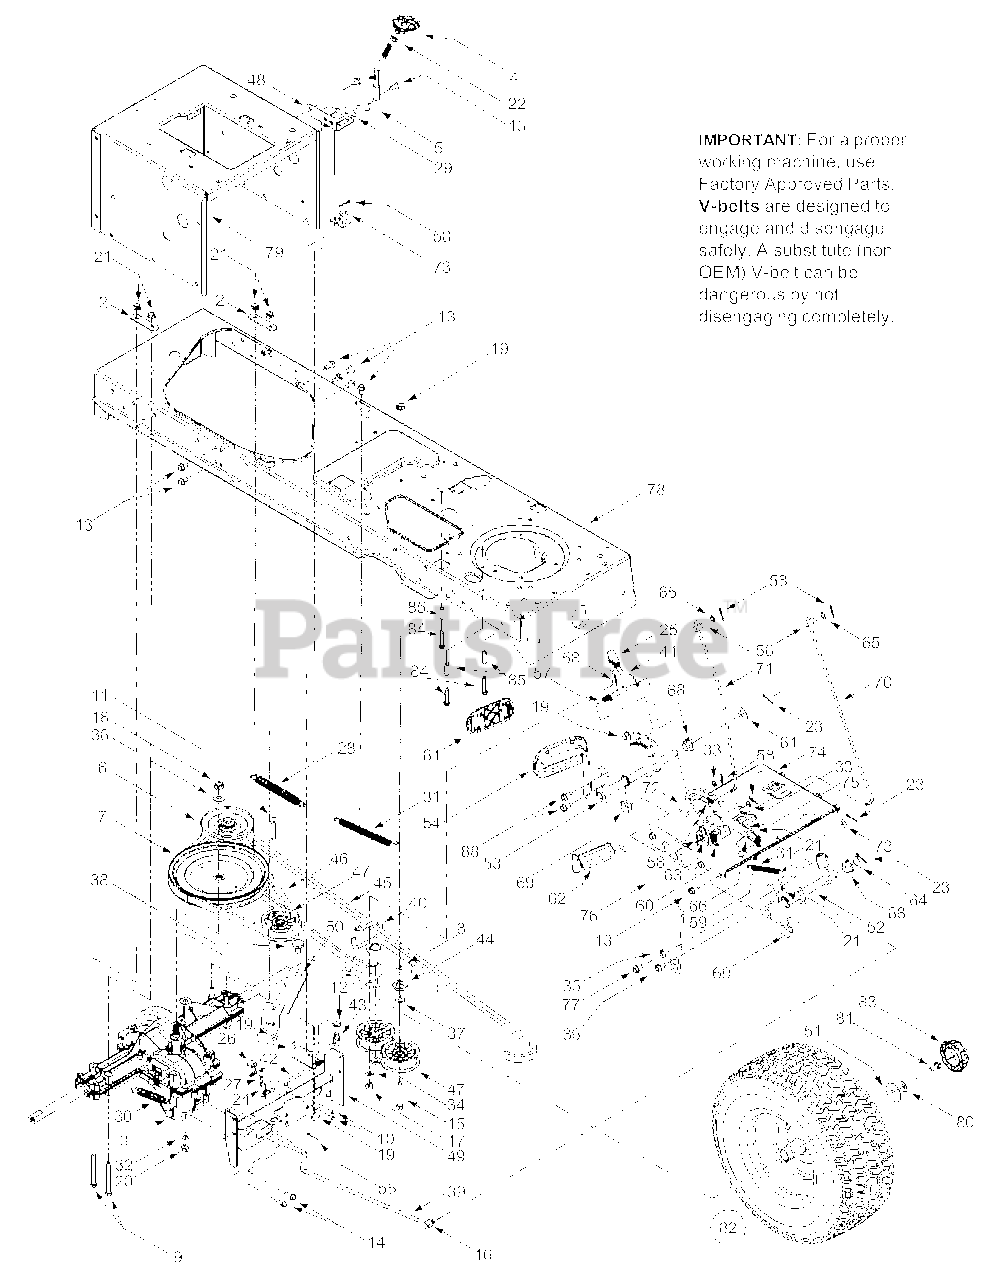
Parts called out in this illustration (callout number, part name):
3	Single-speed Transmission Assembly
4	Shifter Knob
5	Shift Lever
6	Variable-speed Pulley Assembly
7	Transmission Pulley, 8.5 x .5-36
8	Double-idler Bracket
9	Hex Cap Screw, 5/16-18 x 2.75
10	Self-tapping Screw, #8-18 x .5
11	Hex Cap Screw, 3/8-16 x 1.75
12	Flat Washer, .51 x 1.0 x .060
13	Self-tapping Screw, 5/16-18 x .625
14	Self-tapping Screw, 1/4-20 x .75
15	Hex Cap Screw, 3/8-16 x 2.25
16	Ferrule, 5/16-18
17	Hex Nut, 3/8-24
18	Hex Nut, 7/16-20
19	Flange Lock Nut, 3/8-16
20	Hex Nut, 3/8-16
21	Flange Lock Nut, 5/16-18
22	Jam Nut, 3/8-16
23	Cotter Pin
24	Internal Cotter Pin
25	Ball Joint
26	Short Spring Switch
27	Insulator Nut Plate
28	Extension Spring, .62 Dia. x 6.12
29	Compression Spring Clip
30	Extension Spring, .59 OD x 4
31	Extension Spring, .50 Dia. x 6.37
32	Bell Washer, .401 x .87 x .063
33	Flat Washer, .385 x .62 x .063
34	Lock Washer, 3/8
35	Flat Washer, .344 x .750 x .120
36	Bell Washer, .45 x 1.0 x .602
37	Flat Washer, .407 x .812 x .135
38	Shoulder Screw, .625 x .217
39	Brake Rod
40	Belt Guard
41	Idler Adjustment Rod, 3/8
42	Shift Rod
43	Adjustment Ferrule, 1/4-20 x 1.0
44	Shoulder Spacer, .38 ID
45	Lower Drive Belt
46	Upper Drive Belt
47	Flat Idler, 2.75 OD
48	Speed Control Rod Bracket
51	Flat Washer, .350 x 1.59 x .062
52	Brake Control Assembly
53	Speed Control Assembly
54	Drive Pedal Assembly
55	Cotter Pin, 1/8 x 1.25
56	Ferrule, 1/4-20
57	Pin, 3/8-16 x 2.43
58	Cotter Pin
59	Compression Spring, .34 OD x 1.0
60	Extension Spring, .50 OD x 1.41
61	Drive Pedal Pad
62	Brake Pedal Pad
63	Flat Washer, .281 x .5 x .063
64	Flat Washer, .64 x 1.24 x .06
65	Flat Washer, .344 x .062 x .03
66	Shoulder Screw, .437 x 1.62
67	Shoulder Screw, .5 x .434
68	Hex Flange Bearing
69	Split Hex Flange Bearing
70	Cruise Control Rod
71	Brake Lock Control Rod
72	Cruise Latch
73	Flat Washer, .344 x .688 x .065
75	Drive Lockout Bracket
81	Hex Cap Screw, 5/16-24 x .75
83	Deluxe Hub Cap
84	Self-tapping Screw, 1/4-20 x 1.25
85	Spacer
86	Self-tapping Screw, 5/16-18 x .875
88	Self Tapping Screw, 5/16-18 x .625
